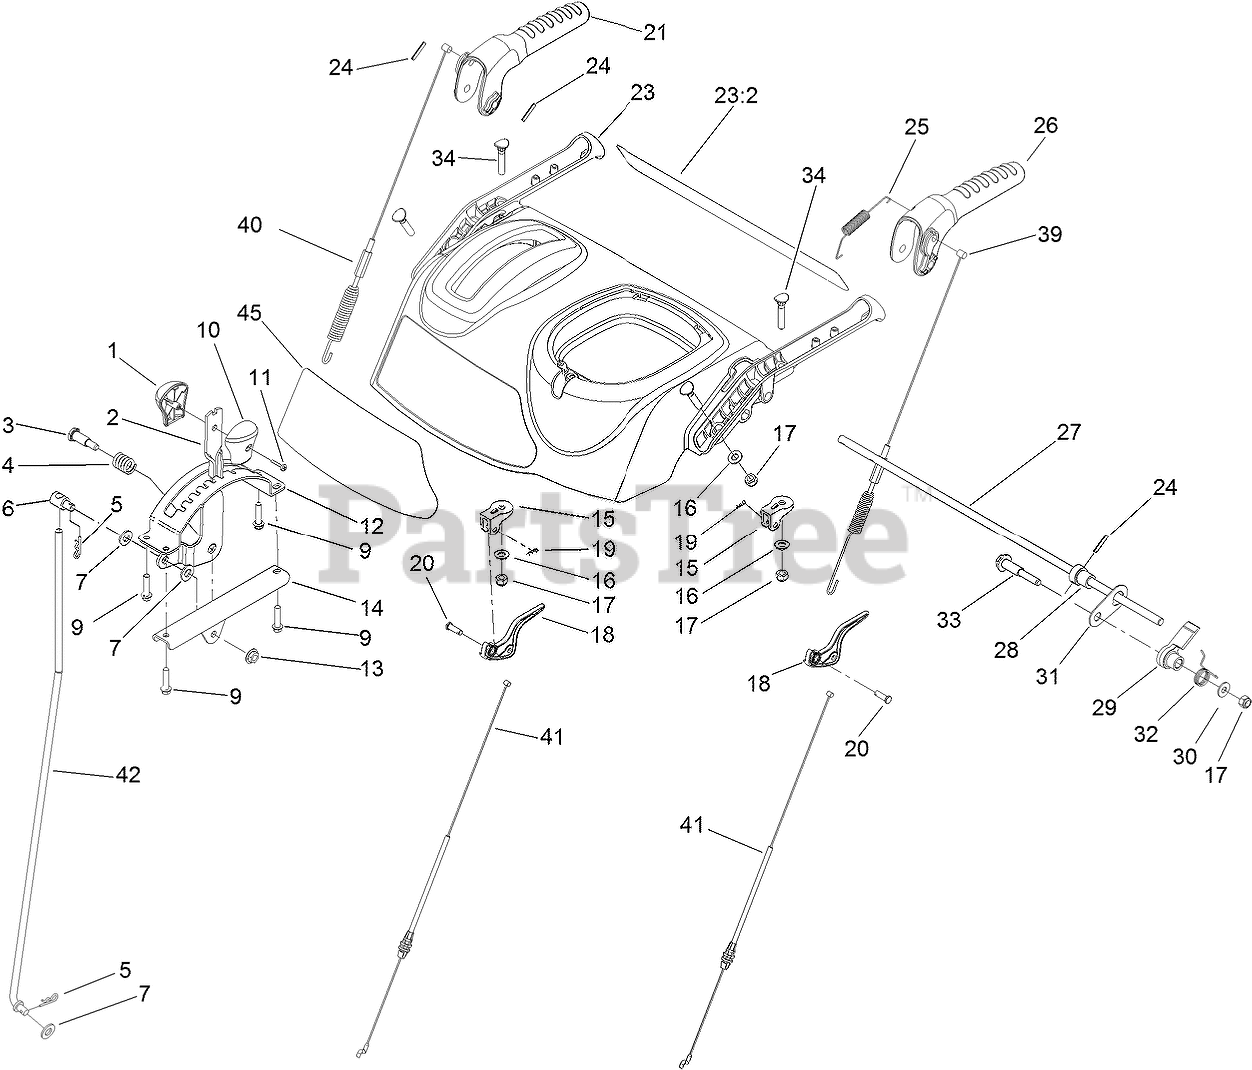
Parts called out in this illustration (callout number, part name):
1	KNOB-SHIFT, RH
2	SELECTOR-SPEED
3	SCREW-SHOULDER
4	SPRING-COMPRESSION
5	PIN-COTTER
6	TRUNNION-ROD
7	WASHER-FLAT
9	SCREW-PLASTITE
10	KNOB-SHIFT, LH
11	SCREW-PPH
12	GUIDE-SELECTOR, SPEED
13	NUT-HF
14	MOUNT-SELECTOR, SPEED
15	MOUNT-CLUTCH, LEVER
16	WASHER-FLAT
17	NUT-LOCK, NI
18	LEVER-CLUTCH
19	PIN-HAIR
20	PIN-CLEVIS
21	LEVER-AUGER
23	PANEL-CONTROL
23:2	DECAL-WARNING
24	PIN-SPRING
25	SPRING-TENSION
26	LEVER-TRACTION
27	ROD-LOCKOUT
28	CAM-LOCKOUT
29	LATCH-LOCKOUT
30	WASHER-FLAT
31	LINK-LOCKOUT
32	SPRING-TORSION
33	SCREW-SHOULDER
34	SCREW-HANDLE
39	CABLE-TRACTION
40	CABLE-AUGER
41	CABLE-CLUTCH
42	ROD-SHIFT
45	DECAL-CONTROL PANEL
